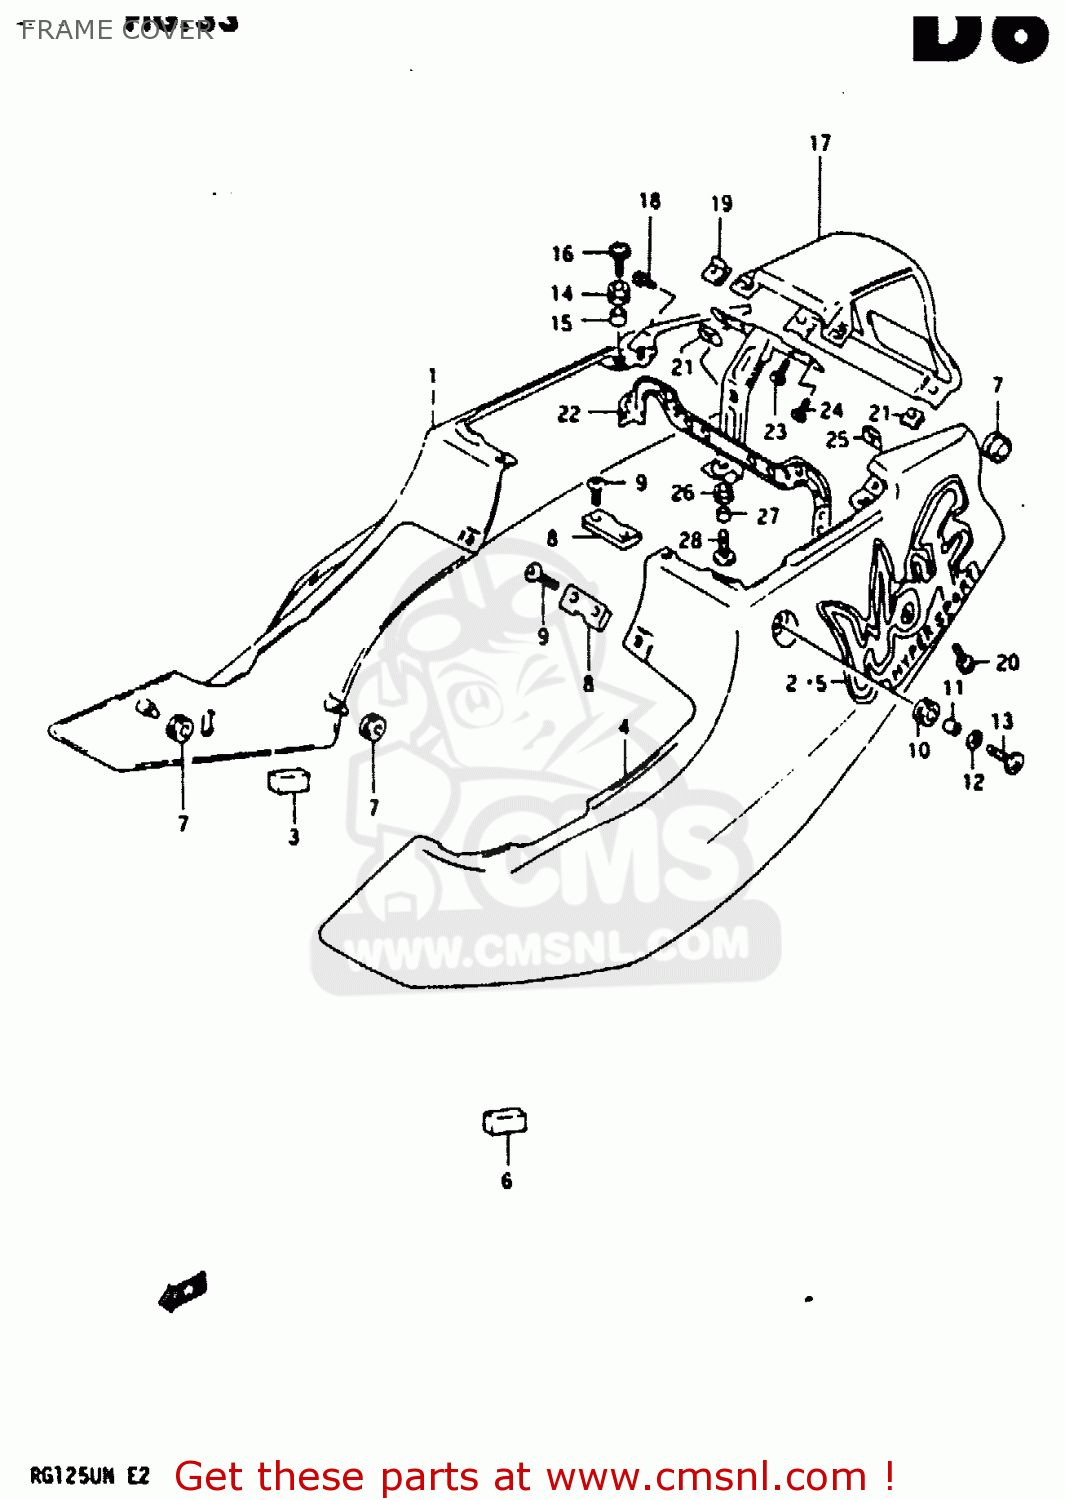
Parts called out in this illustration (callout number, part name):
1	COVER, FRAME RH (RED)
2	EMBLEM, FRAME COVER
3	RUBBER,FRAME COVER
4	COVER, FRAME LH (RED)
5	EMBLEM, FRAME COVER
6	RUBBER,FRAME COVER
7	CUSHION
8	NUT,FRAME COVER CTR
9	SCREW
10	CUSHION
11	SPACER (6.3X9.1X6.7)
12	WASHER(6.5X22X1.6)
13	SCREW(6X20)
14	CUSHION
15	SPACER (6.3X9.1X6.7)
16	SCREW(6X20)
17	COVER, FRAME CENTER (RED)
18	SCREW, BRACKET
19	NUT
20	SCREW
21	NUT
22	BRACKET, TAIL LAMP
23	SCREW
24	SCREW, BRACKET
25	NUT
26	CUSHION
27	SPACER (6.1X8X9.5)
28	BOLT(6X20)
